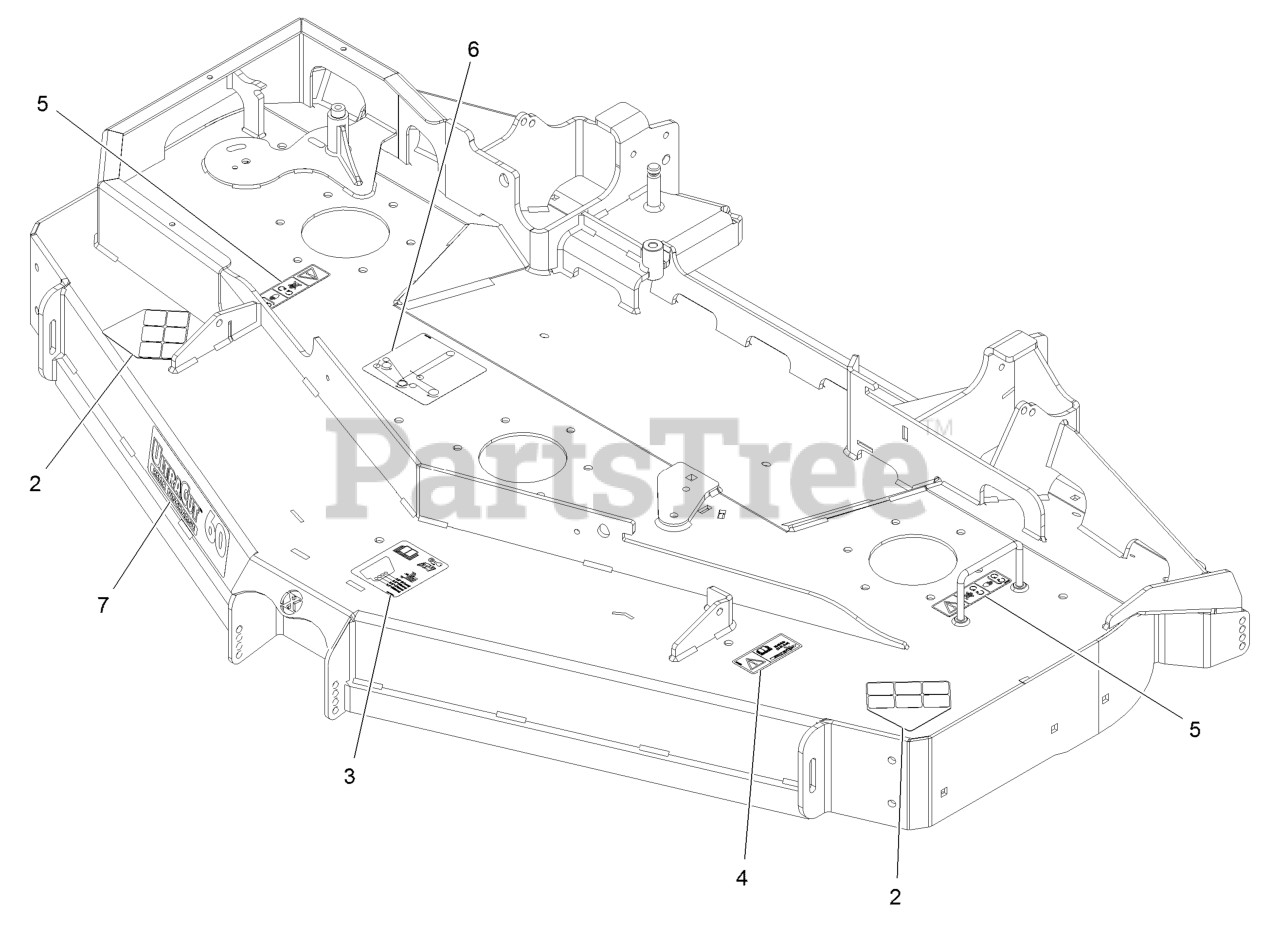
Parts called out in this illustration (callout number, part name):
2	DECAL-DANGER
3	DECAL-ROLLER, ANTI-SCALP
4	DECAL-BOLT TORQUE
5	DECAL-COVER, MISSING
6	DECAL-ROUTING, BELT
7	DECAL,REAR DISCHARGE 60
